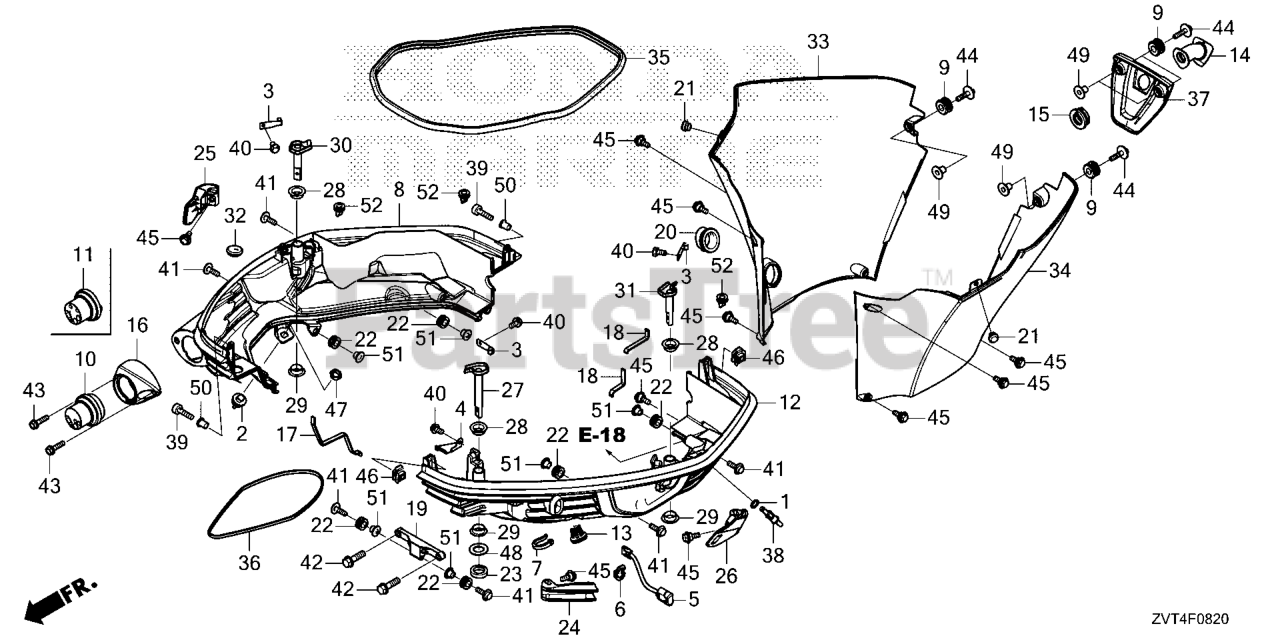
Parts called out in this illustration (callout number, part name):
1	O-RING (1.9X10)
2	CAP, WATER JOINT
3	SPRING, CLICK
4	PLATE, CABLE
5	SWITCH ASSY., POWER TILT
6	STAY, POWER TILT SWITCH
7	BAND (BLACK 3.5X140)
8	CASE, ENG R (LOWER)
9	GROMMET, CASE (LOWER)
10	GROMMET, CASE (LOWER)
12	CASE, ENG L (LOWER)
13	GROMMET, CASE (LOWER) (C)
14	PORT, IDLE EX.
15	GROMMET, IDLE EX.
16	COVER, SEPARATE
17	SEAL A, COVER
18	SEAL B, COVER
19	BRACKET, FR. CASE
20	RUBBER, DRAIN PLUG
21	RUBBER, STOPPER
22	RUBBER, FENDER MOUNTING
23	DAMPER, HOOK
24	LEVER, FR.
25	LEVER, COVER LOCK R
26	LEVER, COVER LOCK L
27	HOOK COMP, FR.
28	COLLAR A, COVER LOCK
29	COLLAR B, COVER LOCK
32	CAP, L. SIDE COVER
33	COVER *NH565*
33	COVER *NHB14M*
34	COVER *NH565*
34	COVER *NHB14M*
35	SEAL A, COVER
36	SEAL B, COVER (LOWER)
37	COVER, RR.
38	GROMMET, WATER CHECK
39	BOLT, SOCKET (6X25)
40	BOLT, FLANGE (6X12) Use from Frame SN 1005249.
41	BOLT-WASHER (6X22)
42	BOLT-WASHER (8X30)
43	BOLT, FLANGE (6X25)
44	BOLT, WASHER (6X25)
45	BOLT, SPECIAL (6X17)
47	NUT, HEX. (16MM) DUAL QTY = (2) (SINGLE)
48	WASHER (15MM)
49	COLLAR (12X6.5)
50	COLLAR, DISTANCE (6.5X9X11.5)
51	COLLAR, DISTANCE (6.2X7.5)
52	GROMMET (1WAY)
